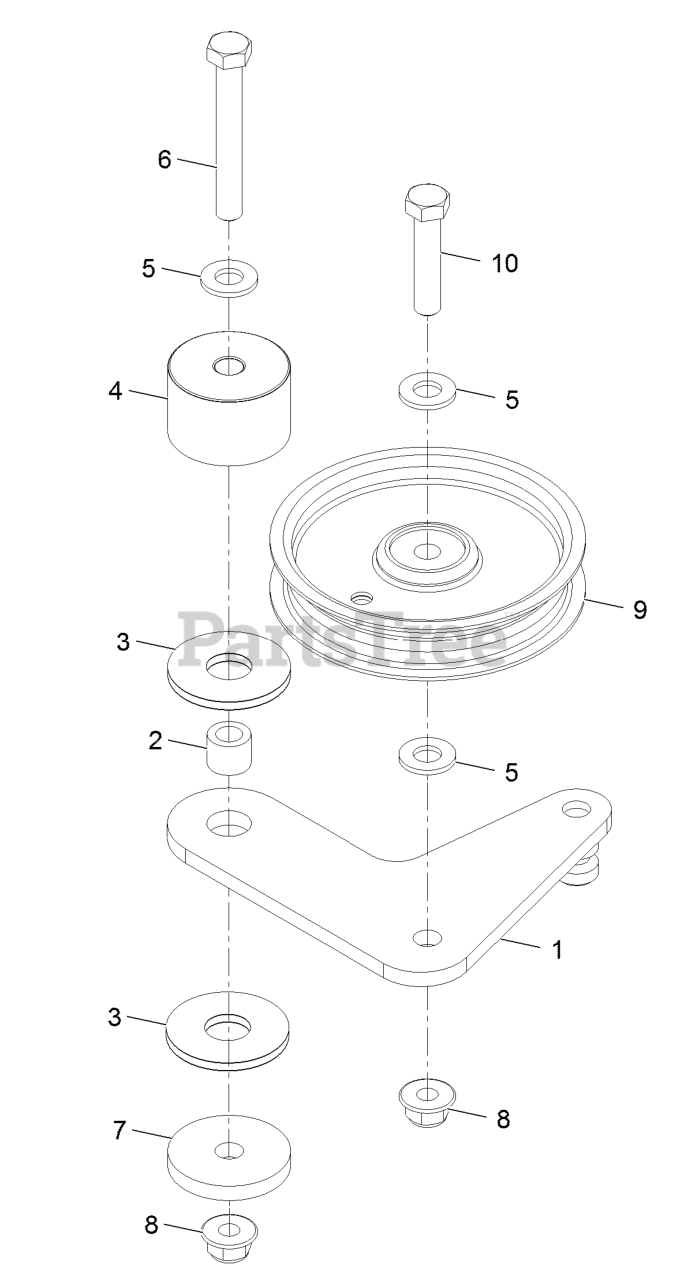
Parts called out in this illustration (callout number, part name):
1	PLATE-IDLER
2	BUSHING-LEVER, LIFT
3	WASHER-FRICTION, COMPOSIT
4	HUB, IDLER
5	WASHER-FLAT
6	SCREW-HH
7	WASHER-PLAIN
8	NUT-HF, NI
9	PULLEY-IDLER
10	SCREW-HH
